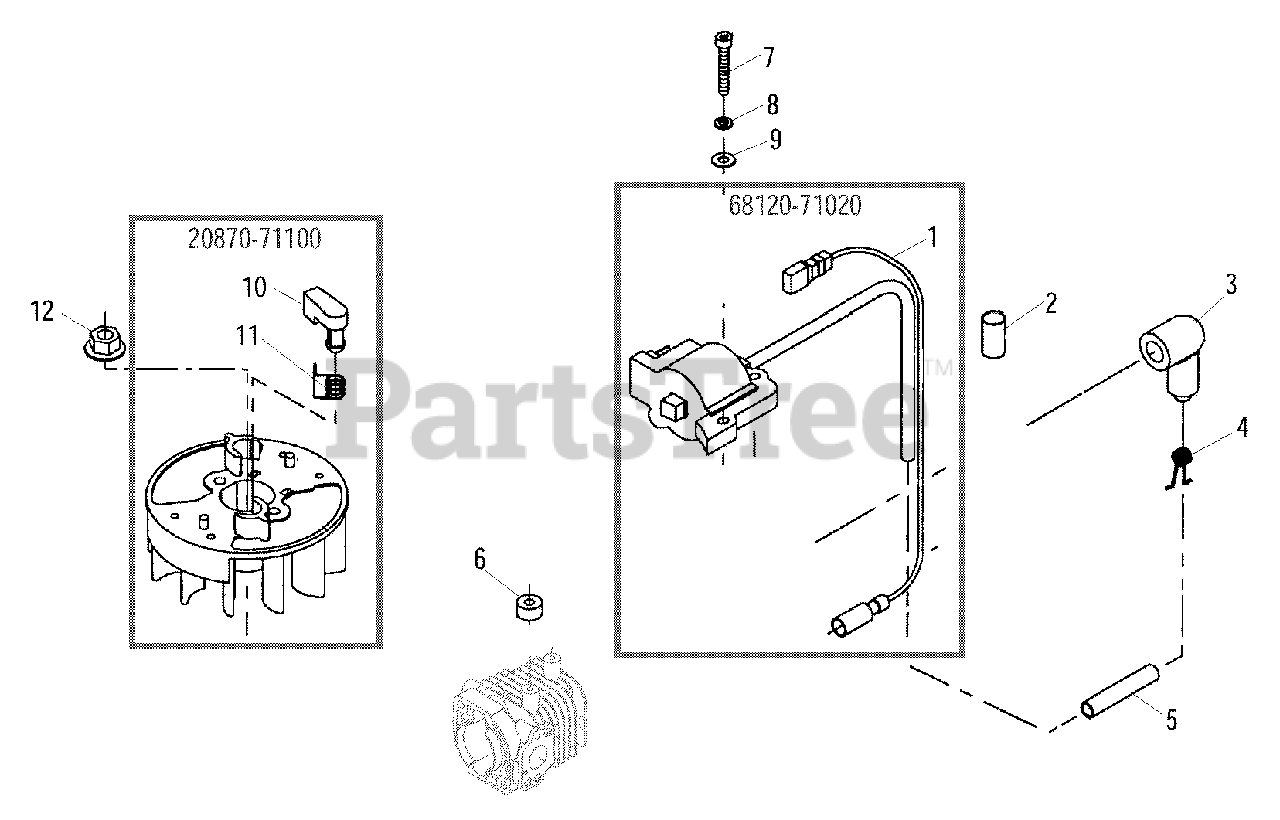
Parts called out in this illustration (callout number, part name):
1	WIRE
2	TUBE
3	CAP, SPARK PLUG
4	TERMINAL, SPARK PLUG CAP
5	TUBE
6	INSULATOR
7	SCREW - 4X26
8	LOCKWASHER - 4
9	WASHER - 4
10	PAWL, STARTER
11	SPRING
12	NUT - 8
20870-71100	FLYWHEEL
68120-71020	IGNITION COIL ASSY
